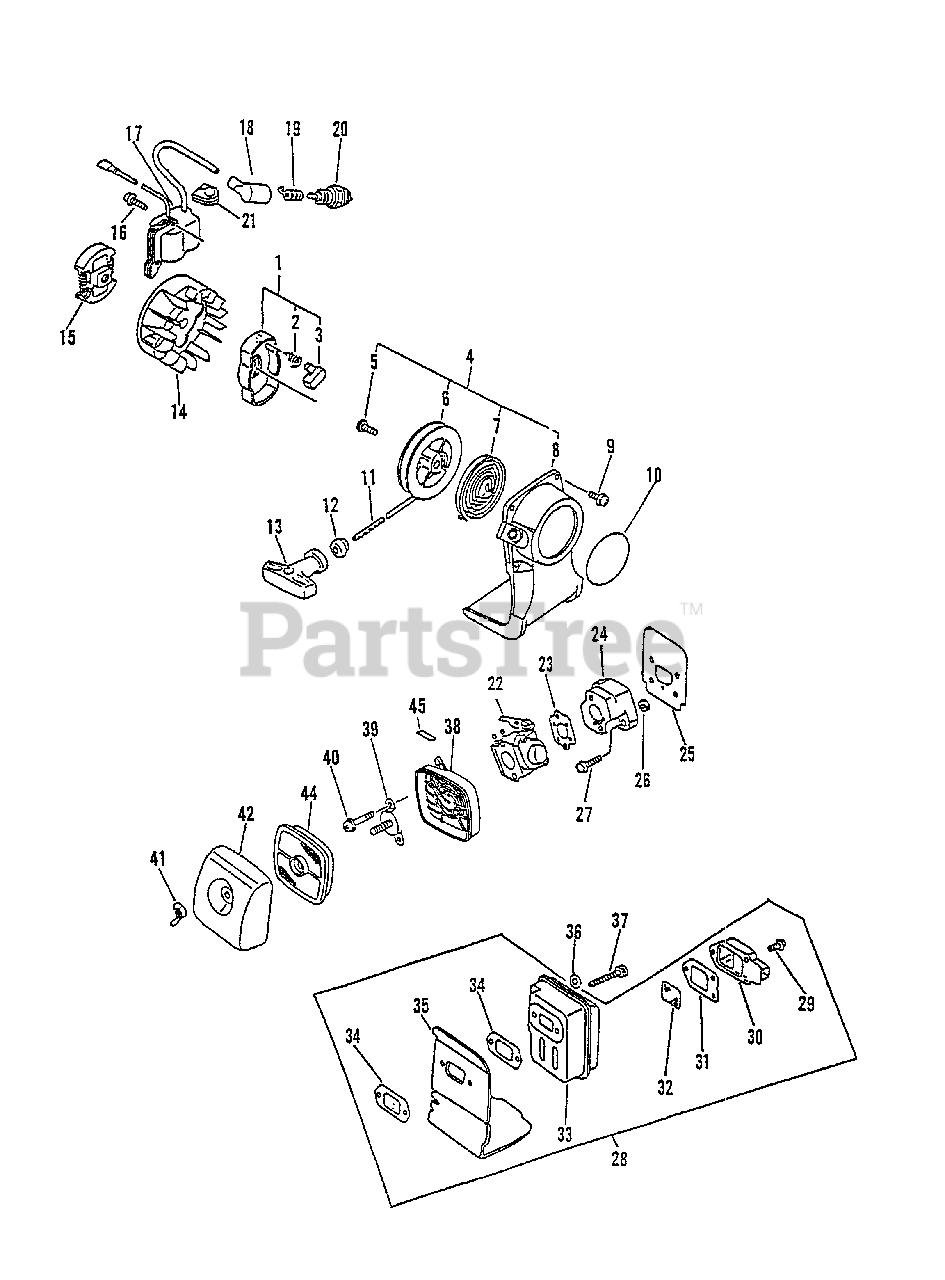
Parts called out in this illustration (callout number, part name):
1	STARTER PAWL ASSY
2	SPRING, RETURN
3	PAWL, STARTER - BLACK
4	STARTER ASSY
6	REEL, ROPE
7	SPRING, REWIND
8	CASE, STARTER - BLUE
9	SCREW - 4X16
10	LABEL - LESCO
11	ROPE, STARTER - 3X890
12	GUIDE, ROPE
13	GRIP, STARTER
14	FLYWHEEL
15	CLUTCH ASSY
16	SCREW - 4X22
17	COIL, IGNITION
18	CAP, SPARK PLUG
19	TERMINAL, SPARK PLUG CAP
20	SPARK PLUG -- BPM-7A
22	CARBURETOR C1U-K16
23	GASKET, INTAKE
24	INSULATOR, INTAKE
25	SHIELD, INTAKE
27	SCREW - 5X20
28	MUFFLER ASSY
29	SCREW - 4X10
30	GUIDE, EXHAUST - OUTER
31	GASKET, EXHAUST
32	SCREEN, SPARK ARRESTOR
33	MUFFLER
34	GASKET, EXHAUST
35	COVER, EXHAUST
36	WASHER - 5
37	SCREW - 5X55
38	AIR FILTER CASE ASSY
39	PLATE, PREVENT
40	SCREW - 5X65
41	WINGNUT - 6
42	COVER, AIR FILTER - BLACK
43	LABEL - TOP
44	FILTER, AIR
45	LABEL - CHOKE
